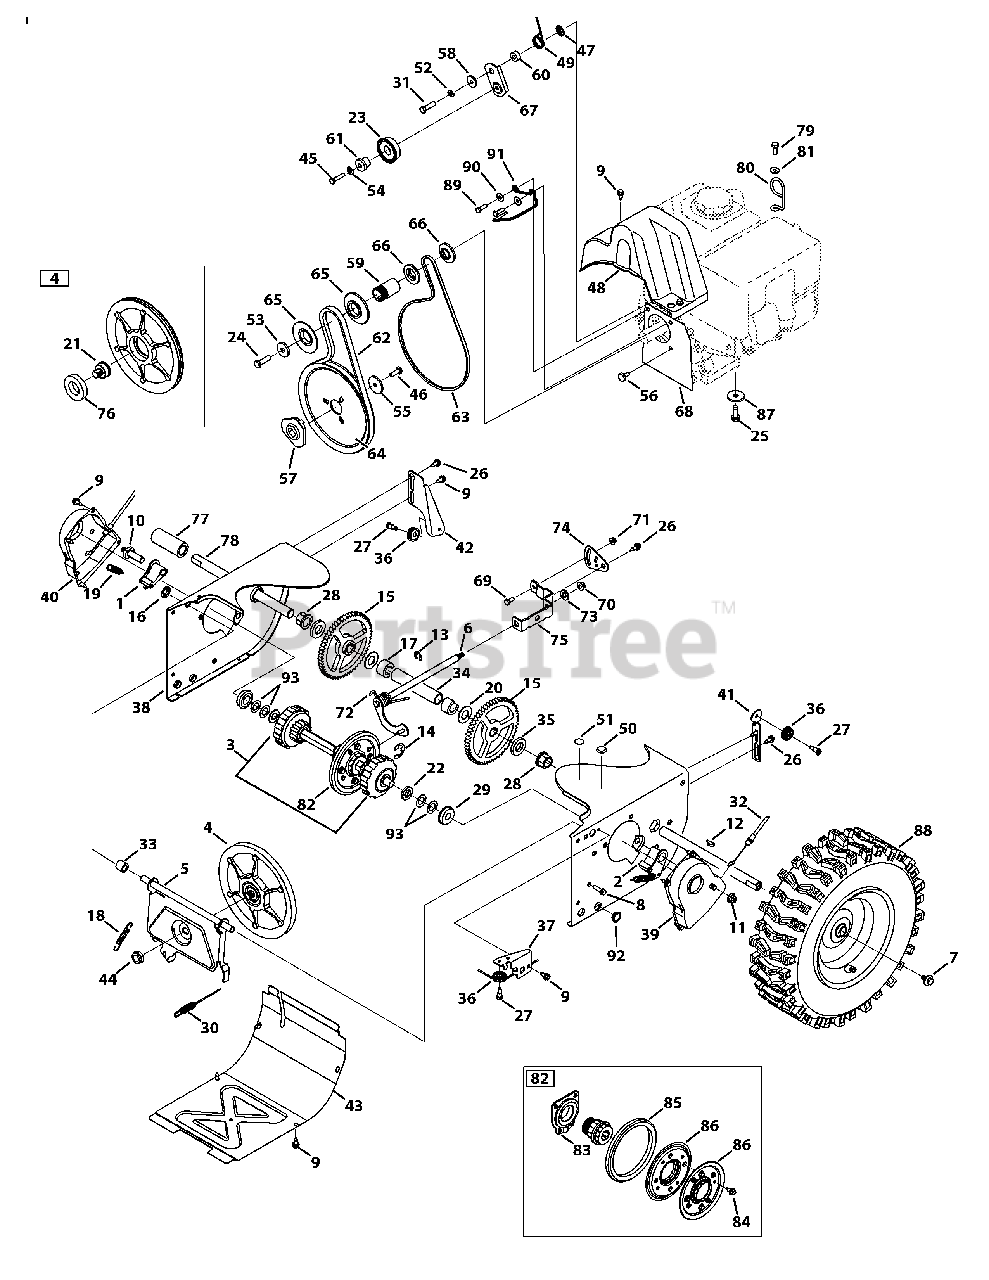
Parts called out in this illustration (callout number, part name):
1	Dogg Assembly, RH
2	Dogg Assembly, LH
3	Drive Shaft Assembly
4	Friction Wheel Disc Assembly
5	Friction Wheel Support
6	Rod Shift Assembly
7	Screw, 5/16-24 x .750
8	Screw, 1/4-20 x 1.000
9	Screw, 1/4-20 x .625
10	Actuator Shaft
11	Nut, Flangelock, 3/8-16
12	Hi-Pro Key, 3/16 x 3/4 DIA
14	Retainer Ring
16	Nut, Speed, .500
17	Spacer, .76 x .75
18	Extension Spring, .380 x 2.500
19	Extension Spring, .500 x 1.71
20	Washer, Flat, .76 x 1.49
21	Friction Pin, Disc Bearing
22	Spacer, .68 ID x 1.25 OD x .20
23	Pulley Assembly
24	Hex Head Screw, 3/8-24 x 1.25
25	Taptite Sems Screw, 3/8-16 x 1.000
26	Screw, Shoulder, .368 x .113 x 1/4-20
27	C Screw, Shoulder, .340 x .335 x 1/4-28
28	Hex Flange Bearing, .75 ID
29	Ball Bearing, 17 x 40 x 12
30	Drive Clutch Cable
31	Hex Head Screw, 5/16-24 x 1.25
32	Steering Cable
33	Spacer, .508 x .75
34	Axle Support Tube
35	Spacer, Axle
36	Roller Cable
37	Auger Cable Guide Bracket
38	Wheel Drive Frame
39	Shaft Retainer, LH
40	Shaft Retainer, RH
41	Auger Clutch Cable Guide Bracket
42	Drive Clutch Cable Guide Bracket
44	Nut, Flange, 5/8-18
45	Taptite Screw, 1/4-20 x 1.250
46	Hex Head Screw, 5/16-24 x .875
47	Nut, Push-On, .25 DIA
48	Belt Cover, 4-Way
49	Spring, Torsion, .850 x .333
50	Plug, 3/8 ID
51	Plug, 1/2 ID
52	Washer, Lock, 5/16
53	Washer, Flat, .45 x 1.5
54	Washer, Lock, 1/4
55	Washer, Flat, .34 x 1.50
56	Screw, Shoulder
57	Pulley Adapter, .75 DIA
58	Spacer, Shoulder, .3175 x .500
59	Spacer, .875 x 1.185
60	Spacer, .340 x .750
61	Spacer, Shoulder, .260 x .785
62	Auger Drive Belt, Standard
63	Wheel Drive Belt, Standard
64	Auger Pulley, 8.1 x .5
65	Pulley, Half, 4L-V x 2.600
66	Pulley, Half, 3/8-V x 1.7160
67	Drive Idler Bracket
68	Cover Plate, Standard
69	Hex Head Screw, 1/4-20 x .620
70	Nut, Flangelock, 5/16-18
71	Nut, Flangelock, 1/4-20
72	Spring, Torsion, .750 x .968
73	Washer, Flat, .469 x .875 x .105
74	Speed Selector Pivot Bracket
75	Speed Selector Shift Bracket
76	Ball Bearing, 30 x 55 x 13
77	Spacer, 1.25 x .75 x 3.00
78	Axle, .75 x 11.12
79	Hex Head Screw, 1.25 x 20
80	Cable Guide
81	Washer, Flat, .330 x .630
82	Friction Wheel Assembly
83	Bearing Assembly, Friction Wheel
84	Screw, 5/16-18 x .750
85	Friction Wheel, 5.5 OD
86	Friction Wheel Plate
87	Washer, Flat, .38 x 1.38
88	X-Trac Wheel, 15 x 5 x 6, LH
88	X-Trac Wheel, 15 x 5 x 6, RH
89	Hex Head Screw, 5/16-24 x 1.00
90	Washer, Flat, .349 x .879
91	Belt Guide
92	Plug, 5/8 Hole
93	Flat Washer, .67 x 1.174 x .02
